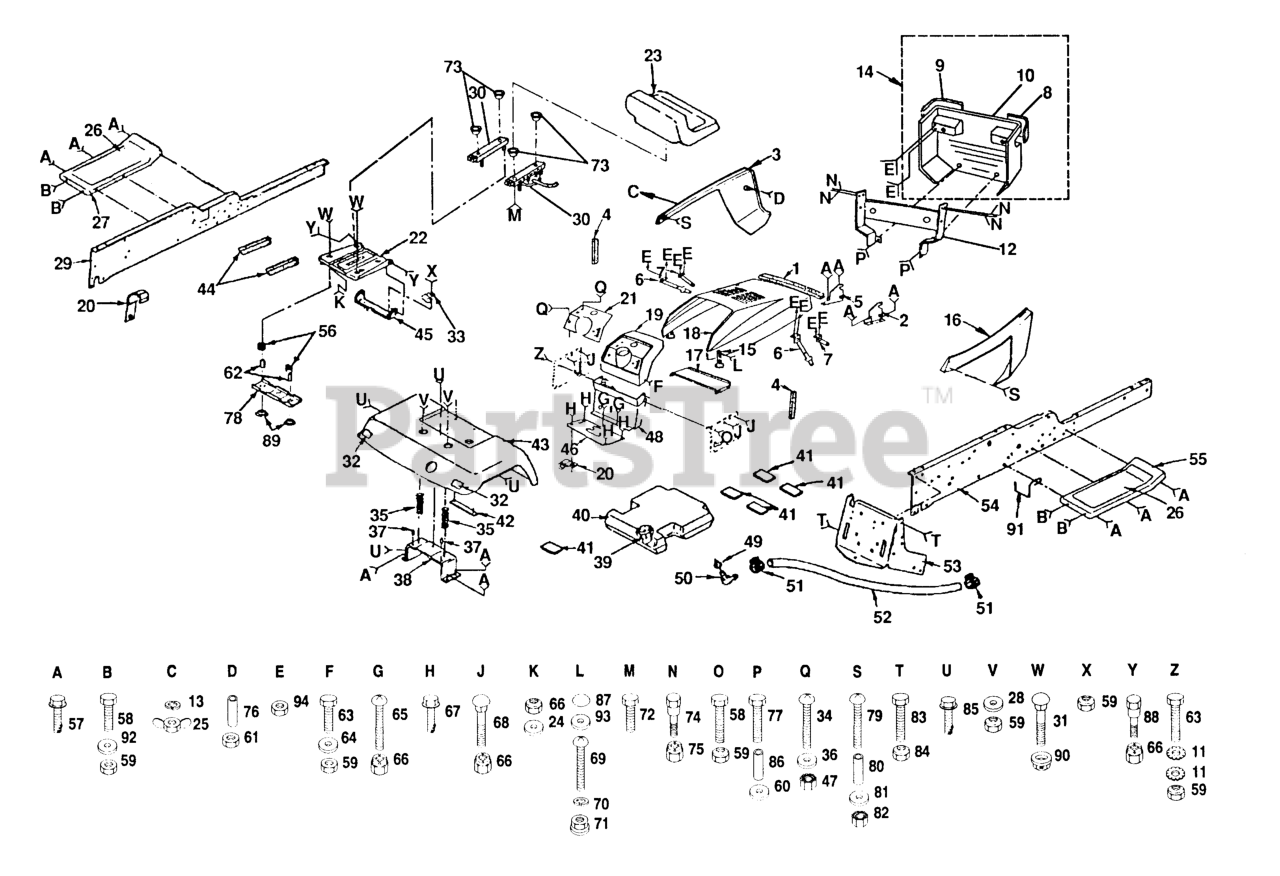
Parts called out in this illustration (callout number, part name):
1	FOAM STRIP T
2	SUPPORT RH YTH
3	PANEL,SIDE LH
4	FOAM STRIP T
5	SUPPORT LH YTH
6	STRAP ASSY LT
7	STRAP ASSY LT
8	LENS RH
9	LENS LH
10	GRILL
11	LOCKWASHER
12	SUPPORT ASS'Y
13	LOCKWASHER GT
14	GRILL COMPLETE
15	LATCH.HOOD.
16	PANEL,SIDE RH
17	BATTERY SUPT GT
18	HOOD
19	DASHBOARD
20	CLIP T
21	DASHPLATE
23	SEAT
25	NUT.WING.LCK.NYL.NOTCH.1/4-20
26	PAD FOOTREST T
27	ROLL PIN NLA
28	WASHER
29	RAIL FRAME T
30	SLIDE SET,SEAT
31	Bolt, Carriage 1/4-20 x 1-1/4
32	REFLECTOR-TAIL YT
33	CLIP T
34	Screw, Mach. Hd. 5/16-18 x 3/4
35	SPRING COMPRESSION
36	WASHER
37	NUT-PUSH YT
38	BRACKET-FENDER YT
39	GAS CAP
40	FUEL TANK W/ SENSOR
41	PAD-SPACER LT
42	STRAP-FENDER YT
43	FENDER
44	STRIP FORM
45	BRKT,SEAT PIVOT
47	NUT
48	DASH ASSY GT
49	BUSHING OUTLET T
50	FUEL TANK STEM GT
51	HOSE CLAMP
52	HOSE
53	DRAWBAR GT
54	RAIL FRAME T
55	PAD,SPACER
56	SPRING COMPRESSED
57	SCREW
60	WASHER PM
61	NUT
62	SPACER SPLIT
63	BOLT
64	WASHER
65	Screw, Mach. Cr. Thrd. 5/16-18 x 3/4
66	LOCKNUT
68	RP BOLT 5/16-18 X3/4 ZN/YEL GR
69	SCREW
70	LOCKWASHER #10
71	WELDNUT
72	Screw, Hex 5/16-18 x 1
74	BOLT T
75	NUT.CROWNLOCK.1/4
76	SPACER NLA
78	BRKT SWITCH
79	RP SCREW
82	NUT **
83	BOLT
84	Locknut 7/16-14
85	SCREW LT
87	SNAP CAP LT
88	BOLT, SHOULDER LT
90	NUT T
91	BELT RETAINER GT
92	WASHER
94	NUT
